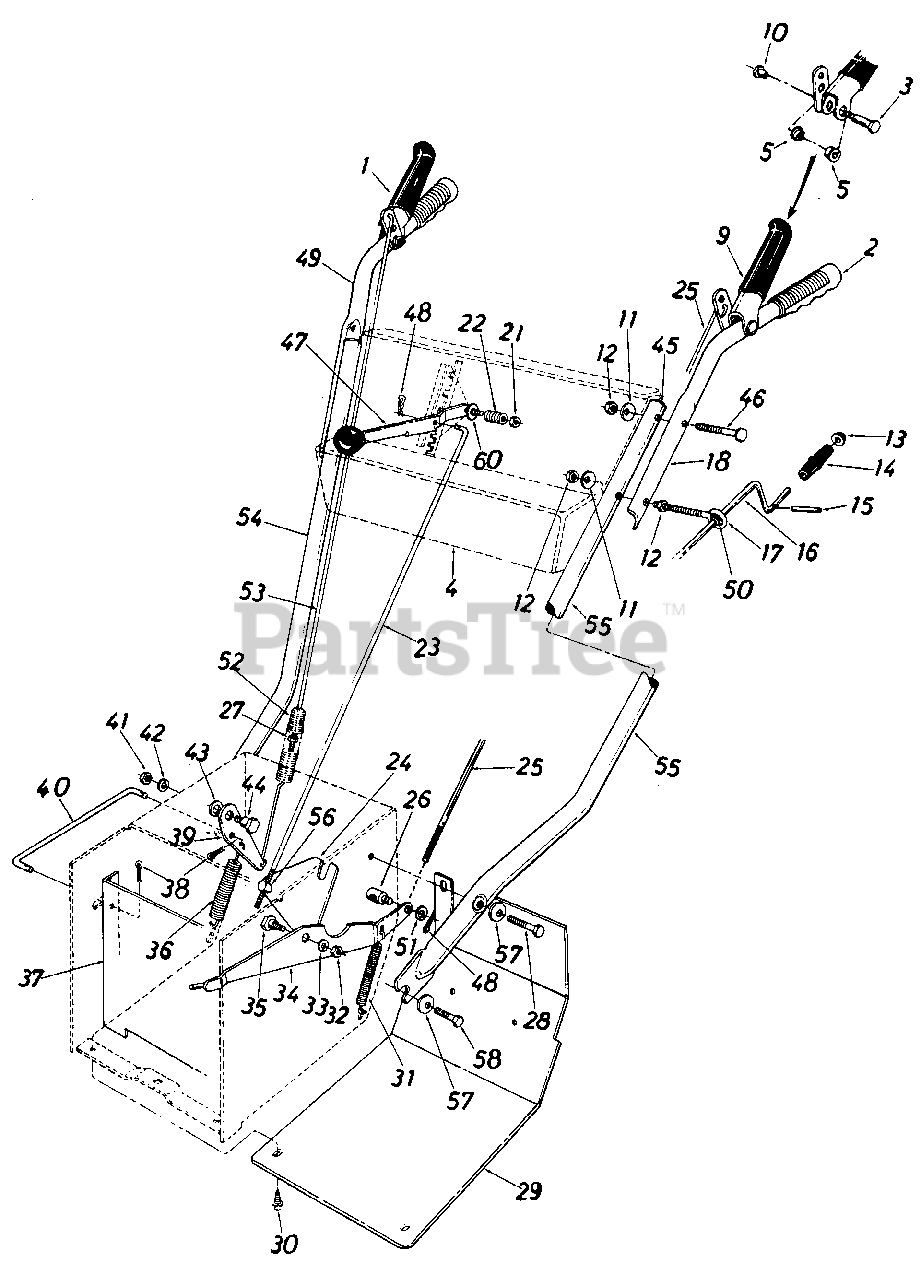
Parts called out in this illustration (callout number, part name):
1	GRIP ASSY-LH CLUTCH 2-STG S/T MTD
2	GRIP-BLACK
3	SCREW-SHLD .374 DIA X1.530
4	PANEL ASSY-HANDLE
5	BEARING-FLANGE
9	GRIP ASSY-LH CLUTCH 2-STG S/T MTD
10	NUT-SHLD
11	WASHER-BELL .337 X .867 X .057
12	NUT-HEX 5/16-18
14	KNOB-CHUTE CRANK
15	PIN-ROLL 1/18 DIA
16	CRANK ASSY-CHUTE
18	HANDLE-UPPER-LH
21	NUT-HEX INS L-3/8-24
22	SPRING-COMPRESSION
23	ROD-SHIFT
24	BRACKET-LINKAGE
25	ROD-CLUTCH
26	FERRULE-ADJ
27	NUT-INS LOCK 1/4-20
28	SCREW-HEX 3/8-16 X 2.00
29	COVER-FRAME
30	SCREW-HEX WASH SF TAPP
31	SPRING-EXTENSION
32	NUT-HEX JAM 3/8-18
33	WASHER-LOCK-3/8
34	BRACKET-AUG CLUTCH
35	SCREW-SHLD .625 DIA X .163
36	SPRING-IDLER EXTN
37	BRACKET ASSY-PULLEY SUP
38	PIN-COTTER-3/32 DIA X .75
39	BRACKET-DRIVE CLUTCH
40	ROD-VAR SP CLUTCH
41	NUT-HEX JAM 3/8-18
42	WASHER-LOCK-3/8
43	WASHER-FL-.344 X .62
44	SCREW-SHLD .625 DIA X .163
46	BOLT-CARRIAGE 5/16-18 X 2.00
47	HANDLE-SHIFT
48	PIN-INTERN COT-5/16 DIA
49	HANDLE-FOLDING-RH
50	BUSHING-.380 ID
51	WASHER-FL-.344 X .62
53	ROD-LOCKOUT
54	HANDLE-LOWER-RH
55	HANDLE-LOWER-LH
56	FERRULE-ADJ
57	WASHER-BELL .400 ID X .88 X .060
58	SCREW-HEX WASH SF TAPP 3/8 X 3/4
60	WASHER-BELL .400 ID X .88 X .060
